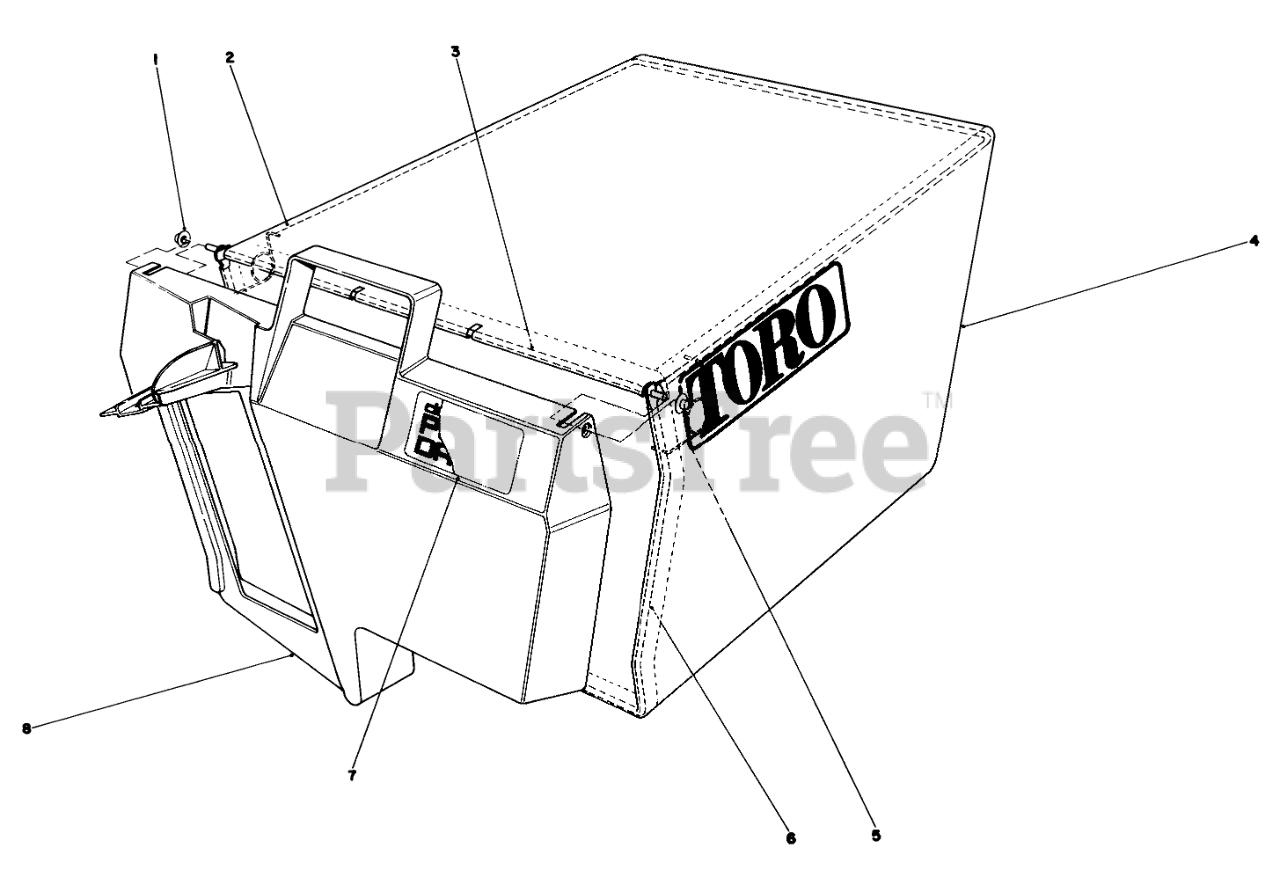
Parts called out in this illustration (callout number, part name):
1	NUT-PUSH
2	FRAME-BAG, UPPER
3	HINGE-DOOR, BAG
4	Bag
5	SPRING
6	FRAME-BAG
7	BAG DOOR DECAL
8	Door Grass Bag
